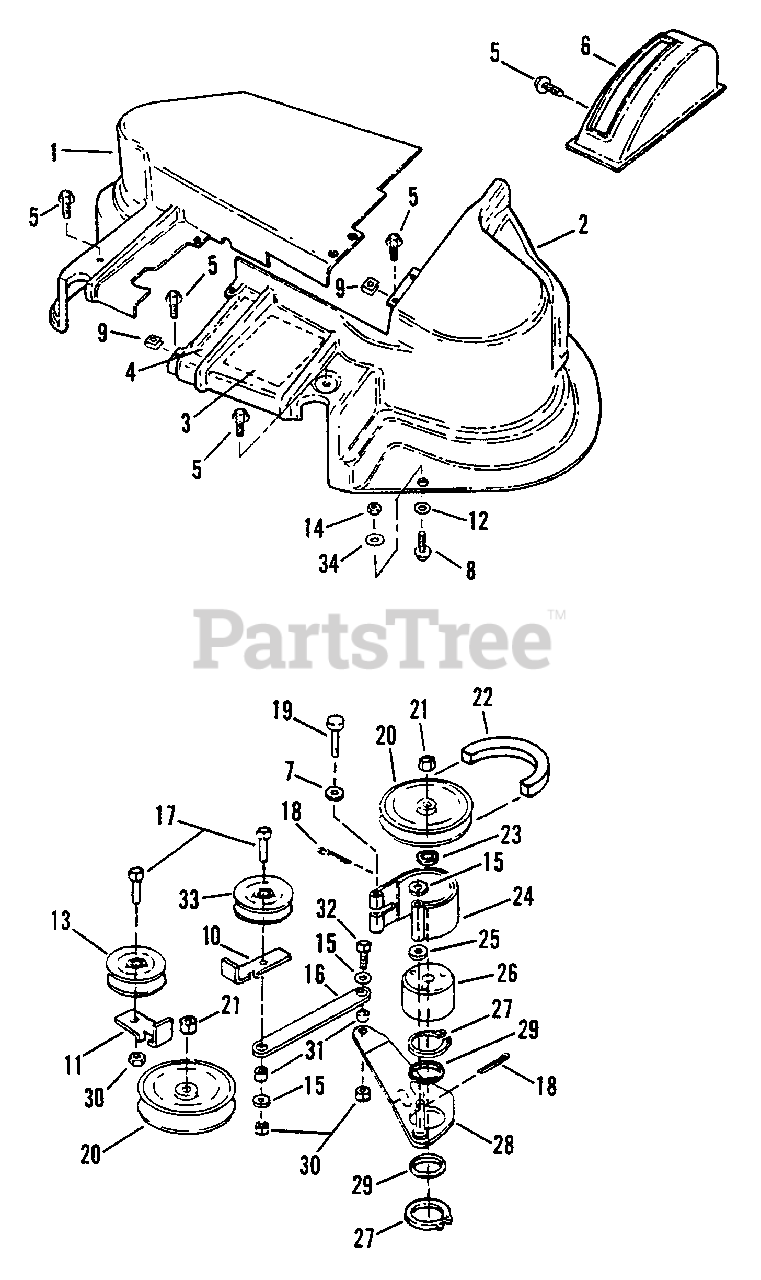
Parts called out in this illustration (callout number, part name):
1	ASSEMBLY, 42" Cover (Right Half)
2	ASSEMBLY, 42" Cover (Left Half)
3	DECAL, Brake Operation
4	DECAL, Blade (ON-OFF)
5	SCREW, 1/4-20 x 5/8" Self-Tapping
6	COVER, Lift Quadrant
7	WASHER, 1/4 Flat
8	BOLT, 3/8-16 x 3/4" Short Neck Carriage
9	NUT, 1/4-20 Tinnerman
10	RESTRICTOR
11	GUIDE, Belt
12	RETAINER, 3/8 Bolt
13	PULLEY, Idler
14	NUT, 3/8-16 Hex Lock
15	WASHER, 3/8" Flat
17	SCREW, 3/8-24 x 1-3/4" Hex Head Cap
18	PIN, 3/32 x 3/4" Cotter
19	PIN, 1/4 x 1-5/8" Clevis
20	PULLEY, 5" O.D.
21	NUT, 3/4-16 Hex Jam
22	BELT, AA105
23	WASHER, 3/4 Flat
24	ASSEMBLY, Brake Band
25	SPACER
26	BRAKE DRUM
27	RING, 2" External Retaining
28	ASSEMBLY, Brake Arm
29	WASHER, 2" I.D.
30	NUT, 3/8-24 Hex Lock
31	SPACER
32	SCREW, 3/8-24 x 3/4" Hex Head Cap
33	PULLEY, Idler
34	WASHER, 3/8" Flat
